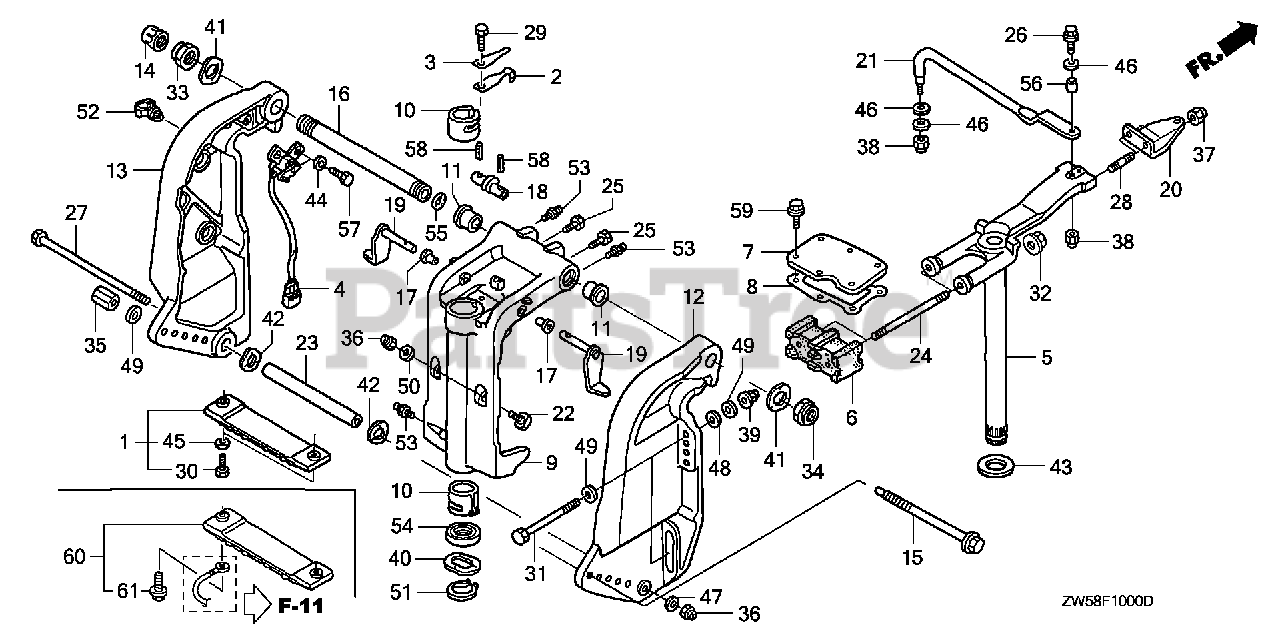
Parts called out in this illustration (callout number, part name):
1	METAL KIT, ANODE
2	SPRING, CLICK
3	SPRING, CLICK ASSIST
4	SENSOR ASSY., TRIM ANGLE
5	FRAME, MOUNTING
6	MOUNT, RUBBER (UPPER)
7	HOLDER, MOUNTING (UPPER)
8	GASKET, MOUNTING HOLDER (UPPER)
9	CASE, SWIVEL *NH282MU* (OYSTER SILVER METALLIC-U)
10	LINER, SWIVEL CASE
11	BUSH, SWIVEL CASE
12	BRACKET, R. STERN *NH282MU* (OYSTER SILVER METALLIC-U)
13	BRACKET, L. STERN *NH282MU* (OYSTER SILVER METALLIC-U)
14	CAP, TILTING BOLT
15	ROD, ADJUSTING
16	SHAFT, TILTING
17	BUSH, TILT ARM
18	BRACKET, TILTING
19	STOPPER, TILT
20	PLATE, STEERING
21	ROD, STEERING
22	RECEIVER, THRUST
23	COLLAR, CYLINDER (LOWER)
24	BOLT, STUD (12X150)
25	BOLT (1/4-28UNF)
26	BOLT (3/8-24UNF)
27	BOLT, HEX. (10X235)
28	BOLT, STUD (10X28)
29	BOLT, HEX. (6X14)
30	BOLT, HEX. (6X25)
31	BOLT, HEX. (12X119)
32	NUT, FLANGE (12MM)
33	NUT, SELF-LOCK (7/8-14UNF)
34	NUT, SELF-LOCK (25X2.0)
35	NUT, ADJUSTER ROD
36	NUT, SELF-LOCK (10MM)
37	NUT, SELF-LOCK (10MM)
38	NUT, SELF-LOCK (3/8-24UNF)
39	NUT, SELF-LOCK (12MM)
40	WASHER, WAVE (40MM)
41	WASHER, WAVE (26MM)
42	WASHER, WAVE (32MM)
43	WASHER, THRUST (34MM)
44	WASHER, PLAIN (6MM)
45	WASHER, PLAIN (6MM)
46	WASHER (10MM)
47	WASHER, PLAIN (10MM)
48	WASHER, PLAIN (12MM)
49	WASHER, PLAIN (12MM)
50	WASHER, PLAIN (10MM)
51	CIRCLIP (OUTER) (39MM)
52	CLIP, WIRE HARNESS
53	NIPPLE, GREASE
54	OIL SEAL (39.5X52X6) (ARAI)
55	O-RING (15.54X2.62)
56	COLLAR, STEERING ROD
57	BOLT, HEX. (6X20)
58	PIN, SPRING (2.5X20)
59	BOLT, FLANGE (8X35)
